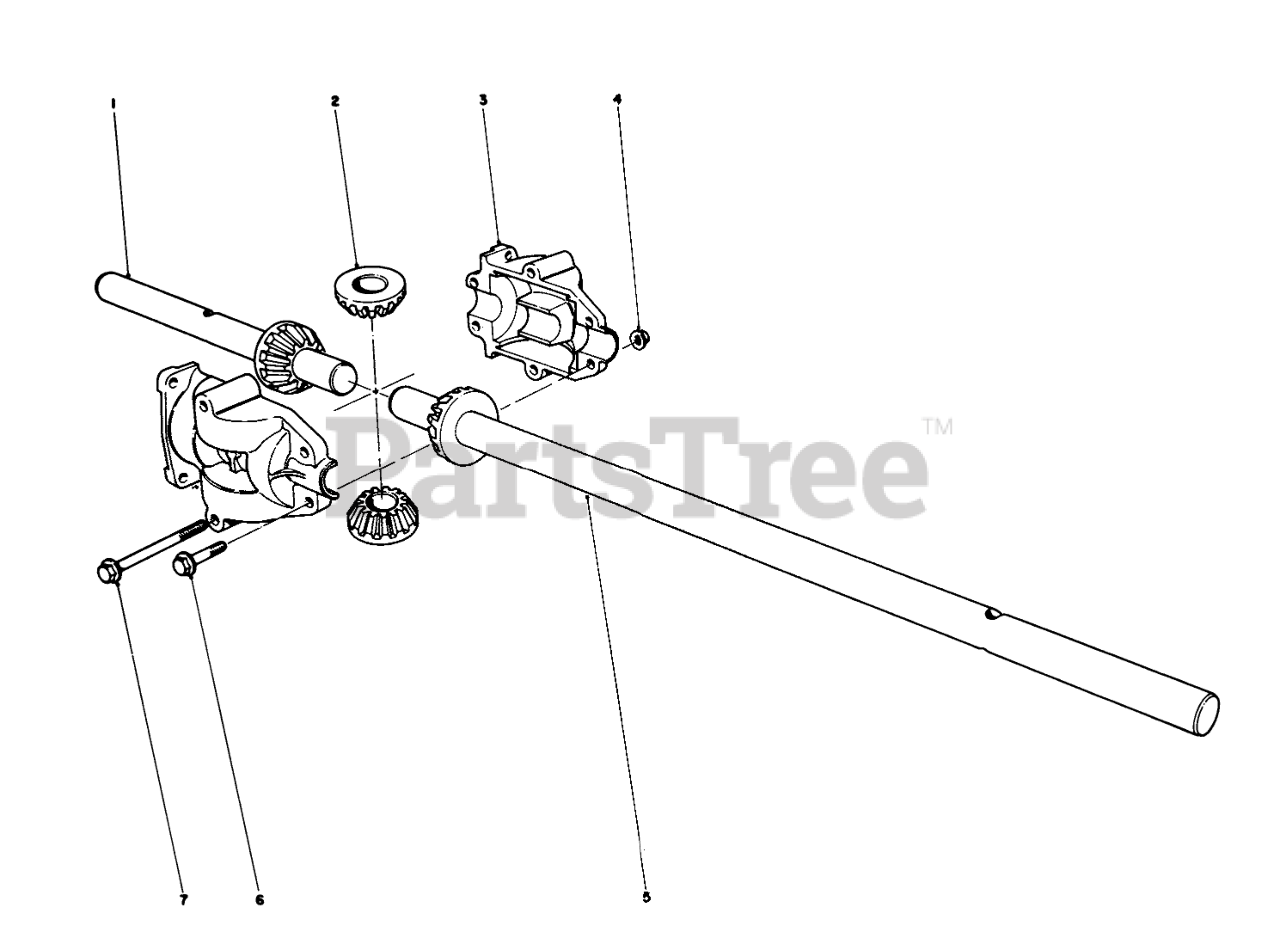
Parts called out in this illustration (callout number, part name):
1	SHORT SHAFT
2	MITER GEAR
3	DIFF HSG
4	NUT-HHF
5	LONG SHAFT
